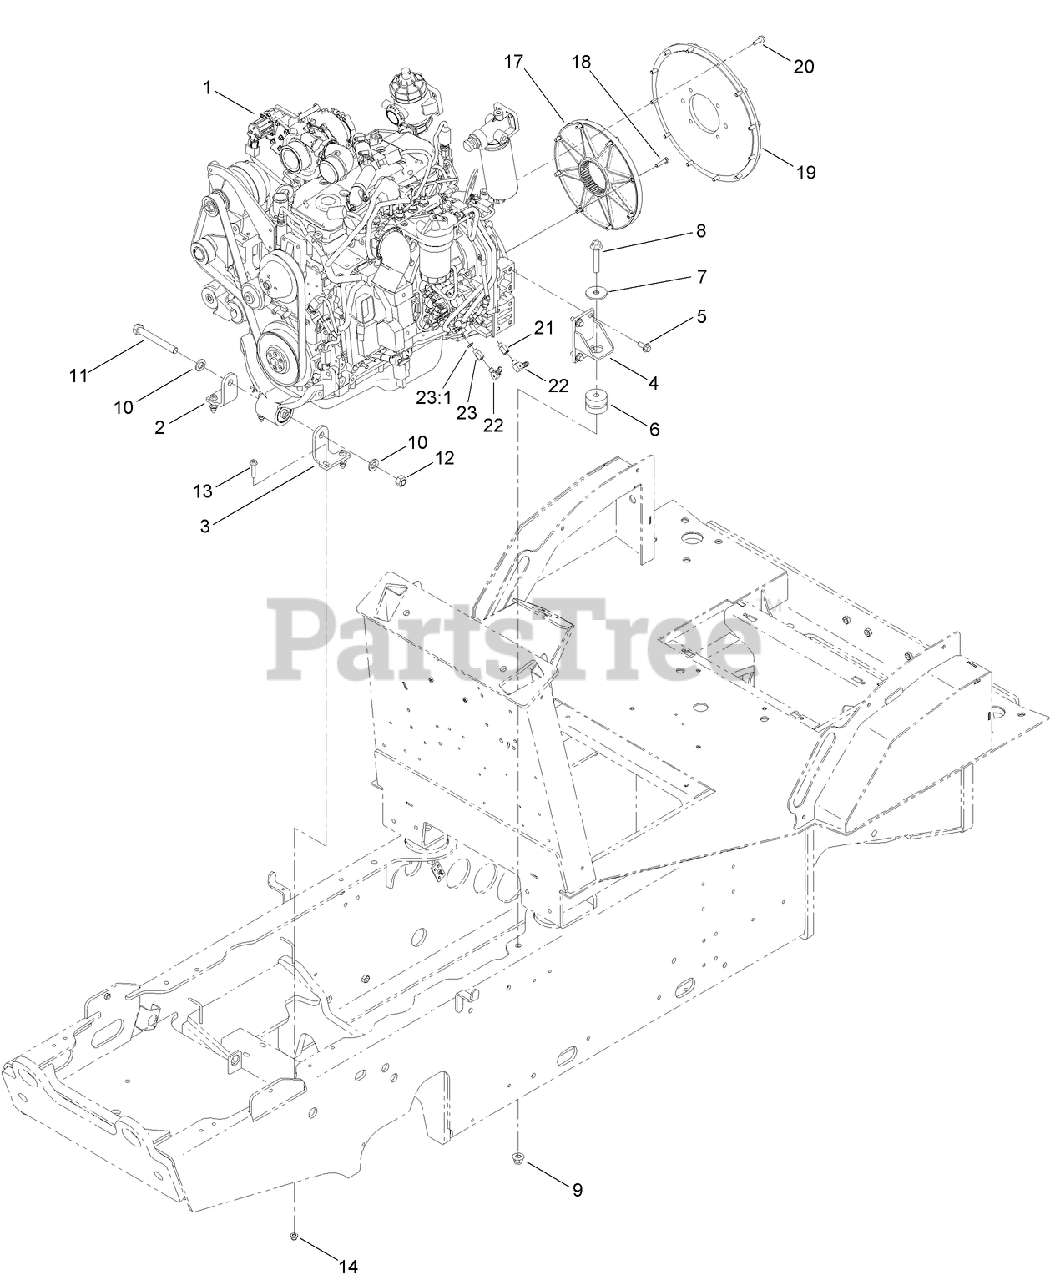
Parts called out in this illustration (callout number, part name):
1	ENGINE ASM
2	BRACKET-ENGINE SUPPORT, LH
3	BRACKET-ENGINE SUPPORT, RH
4	MOUNT-ENGINE, REAR
5	SCREW-HHF
6	ISOLATOR-WEAR PLATE, GREEN
8	SCREW-FLANGE
9	NUT-HHF
11	SCREW-HH
12	NUT-LOCK
13	SCREW-FLANGE
14	NUT-FLANGE, NYLOCK
17	COUPLING-DRIVE, NYLON
18	SCREW-HH
19	PLATE-MOUNTING, PUMP
20	SCREW-HH
21	FITTING-REDUCER
22	FITTING-ELBOW, 90
23	FITTING-REDUCER
23:1	SEAL-FITTING, FUEL
